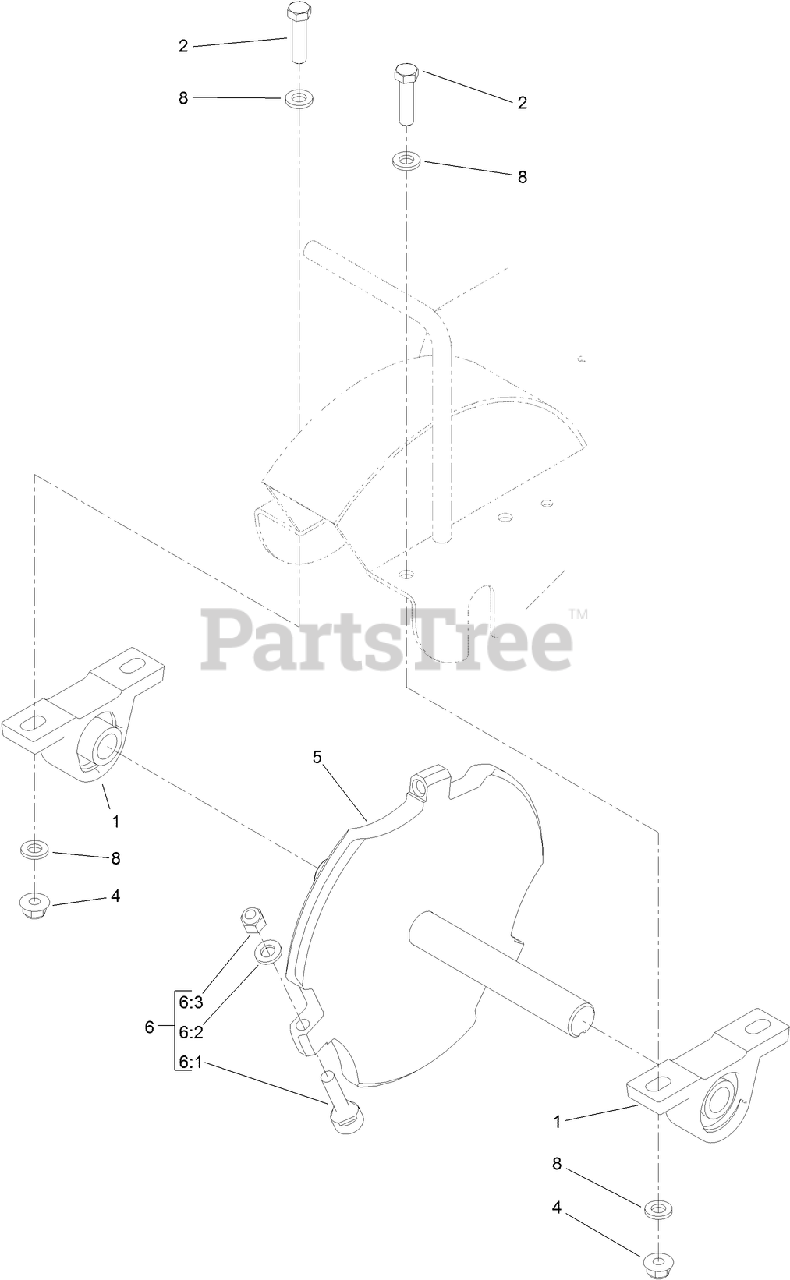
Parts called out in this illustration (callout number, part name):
1	BEARING
2	SCREW-HH
4	NUT-FLANGE, LOCK
5	WHEEL-GRINDER
6	GRINDER TOOTH KIT (SINGLE)
6	GRINDER TOOTH KIT (3-PACK)
6	GRINDER TOOTH KIT (6-PACK)
6:1	TOOTH-GRINDER
6:2	WASHER-HARDENED
6:3	NUT-LOCK
8	WASHER-HARDENED
